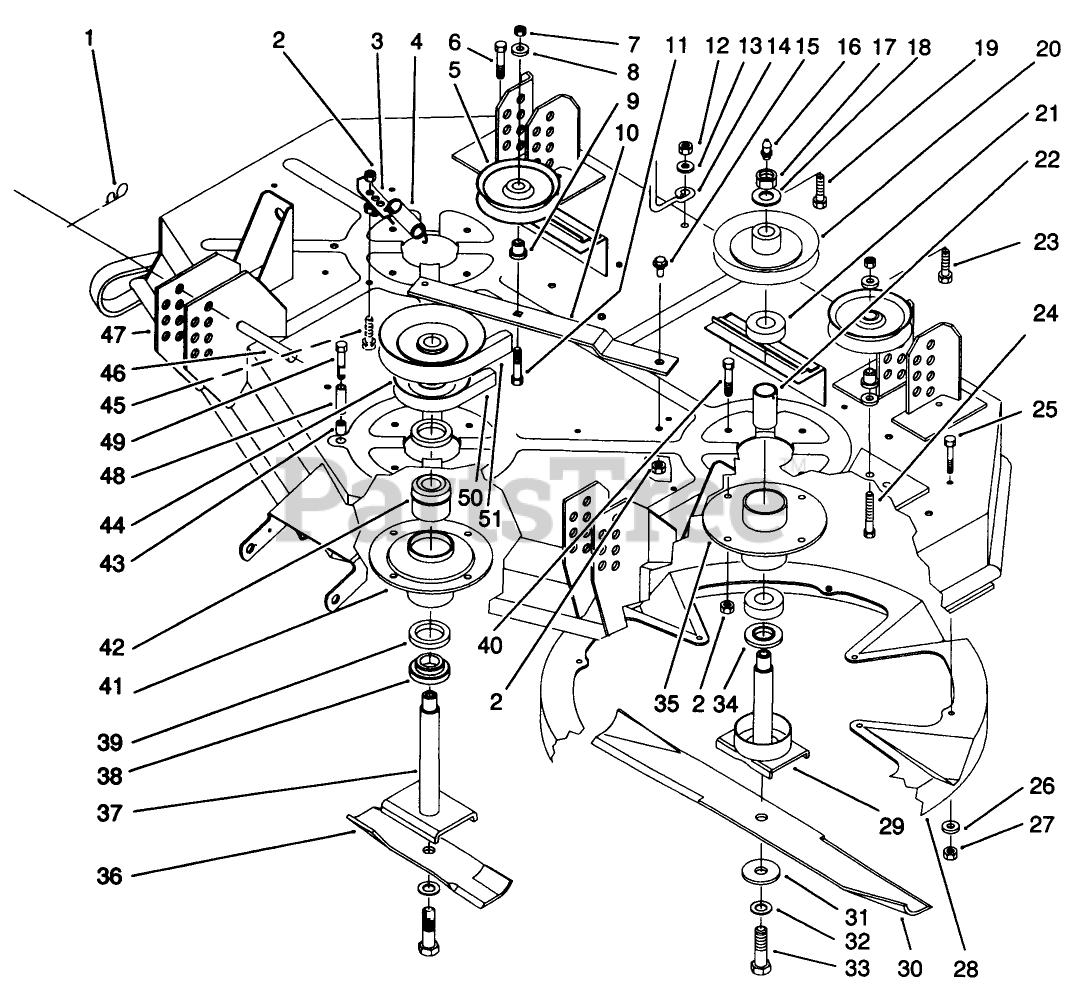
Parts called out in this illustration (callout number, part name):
1	PIN-HAIR
2	NUT-LOCK, NI
3	ANCHOR SPRING R
4	SPRING-EXTENSION, DECK
5	PULLEY-IDLER
6	SCREW-HH
7	NUT-LOCK, NI
8	WASHER-FLAT
9	BUSHING-PULLEY
10	IDLER LEVER R
11	SCREW-HH
12	NUT-HF
13	WASHER-FLAT
14	BELT ROD
15	SCREW-SHOULDER
16	FITTING-GREASE
17	NUT-HEX
18	WASHER
19	SCREW-HH
20	PULLEY-DECK
21	BEARING-BALL
22	SPACER-BEARING
23	SCREW-HH
24	SCREW-HH
25	SCREW-HH
26	WASHER-FLAT
27	NUT-LOCK, NI
28	KICKER INSERT
29	SHAFT-SPINDLE
30	L/H BLADE
31	BLADE WASHER
32	WASHER-LOCK
33	SCREW-BLADE
34	SPACER-SPINDLE
35	HOUSING-SPINDLE
36	CENTER BLADE
37	SHAFT-SPINDLE
38	SPACER
39	SEAL-OIL
40	SCREW-HH
41	SPINDLE HOUSING
42	BEARING ASM
43	INSERT-THREADED
44	CENTER PULLEY WA
45	SCREW-HH
46	PIN-CLEVIS
47	DECK W/DECALS
48	OUTER TUBE SPACER
49	SCREW-HH
50	V-BELT
51	V-BELT
